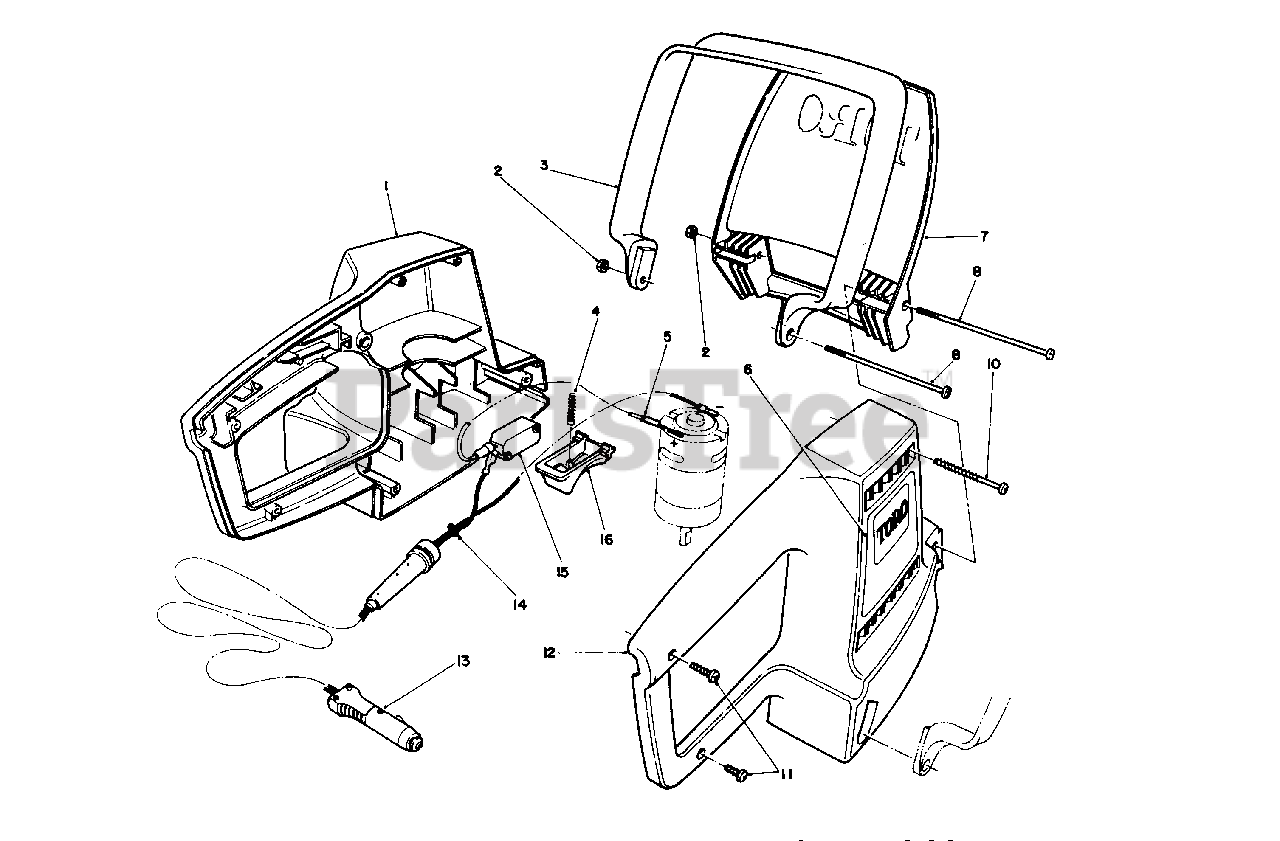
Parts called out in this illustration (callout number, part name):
1	Housing-Handle, L.H.
3	Handle-Assist
5	Wire Assembly
6	Decal-Toro
10	Screw-Thread Forming
11	Screw-Thread Forming
12	Housing-Handle, R.H.
13	Cord-Handle
14	Relief-Strain
16	Trigger-Switch
